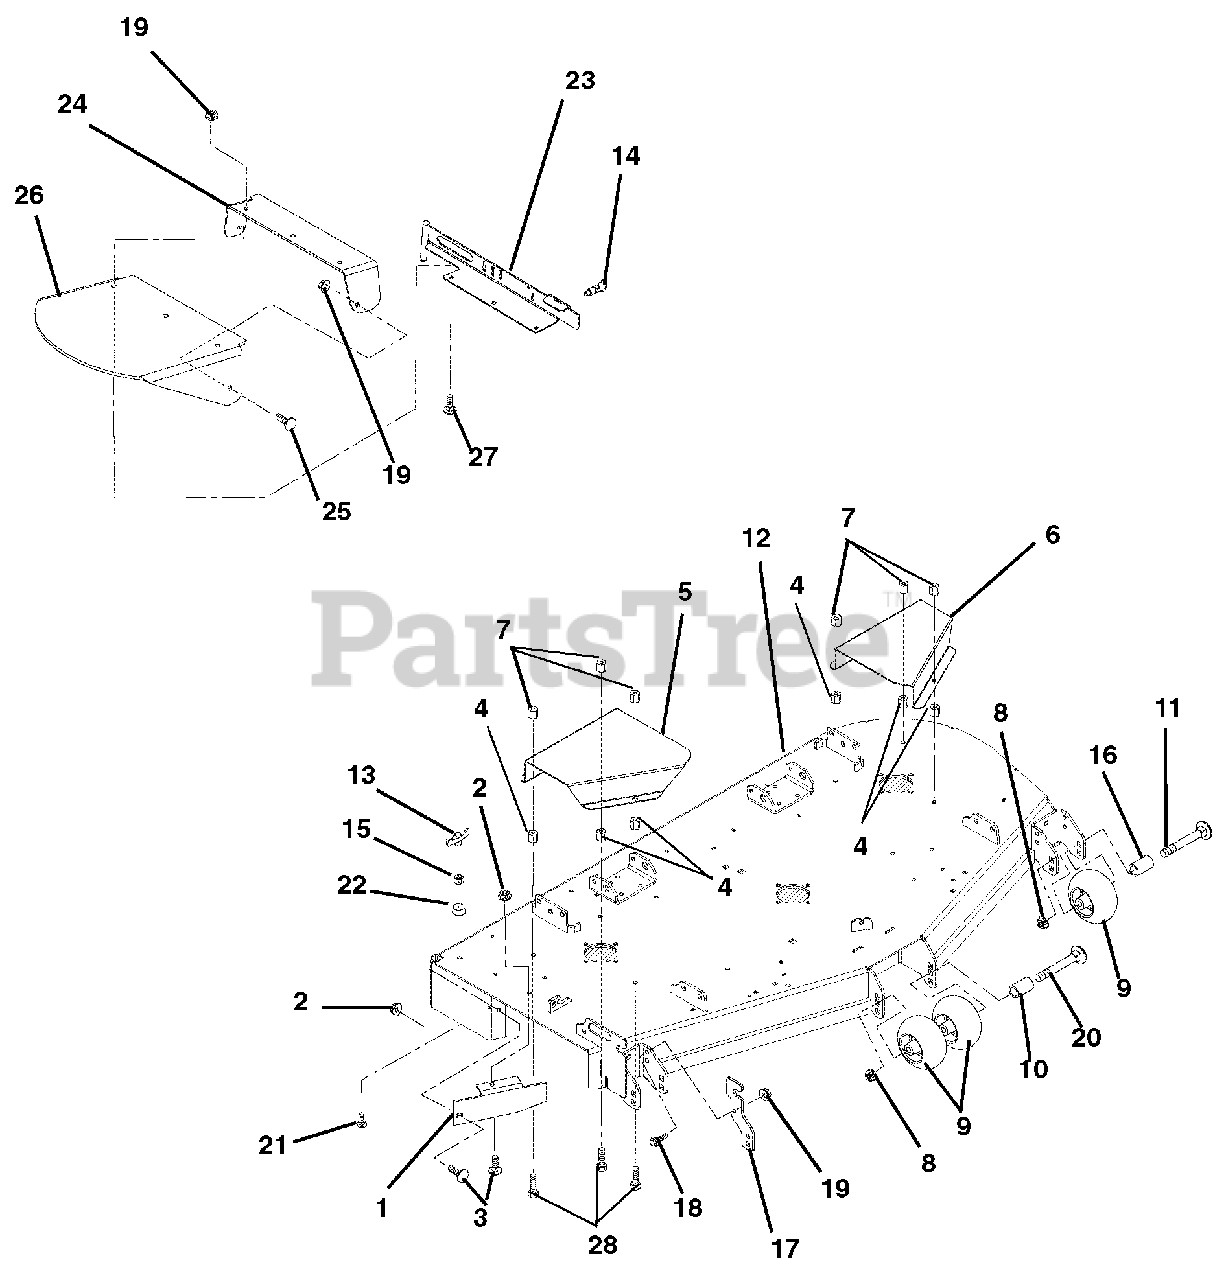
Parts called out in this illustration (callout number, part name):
1	60-in. Discharge Baffle
2	Nut, .31-18 Nyloc Flange
3	Bolt, Round Head Square Neck .31-18 x 1.00 Grade 5
4	Nut, Heavy Hex .38-16
5	Belt Guard, 60-in. Right Hand Deck
6	Belt Guard, 60-in. Left Hand Deck Belt Guard
7	Nut, Spin Lock-Flange .375-16
8	Nut, .50-13 Nyloc Flange
9	Wheel, Anti-Scalp 5 x 3
11	Bolt, Round Head Square Neck .50-13X5.00
12	Deck, 60-in. Side Discharge Mower
13	Knob, Clamping .312-18
14	Pin, Plunger Pull .50-13 Thread x .310 Diameter
15	Nut, Locking, Center .31-18
16	Spacer, .510 x .625 x 3.35
17	Chute, Storage Bracket
18	Bolt, Hex .38-16 x 1.00
19	Nut, .38-16 Nyloc Flange
20	Bolt, Round Head Square Neck .50-13 x 8.50
21	Bolt, Round Head Square Neck .31-18 x 1.50
22	Bumper, Recessed 1.50 x .63, .31 Thru Hole
23	52-inch and 60-inch Discharge Chute Mounting Weldment
24	Rubber Discharge Chute Support
25	Bolt, Round Head Square Neck .38-16 x 1.00 Grade 5
26	Chute, Rubber Discharge
27	Bolt, Round Head Square Neck .38-16 x 1.25 Grade 5
28	Bolt, Hex .38-16 x 1.25 Grade 5
